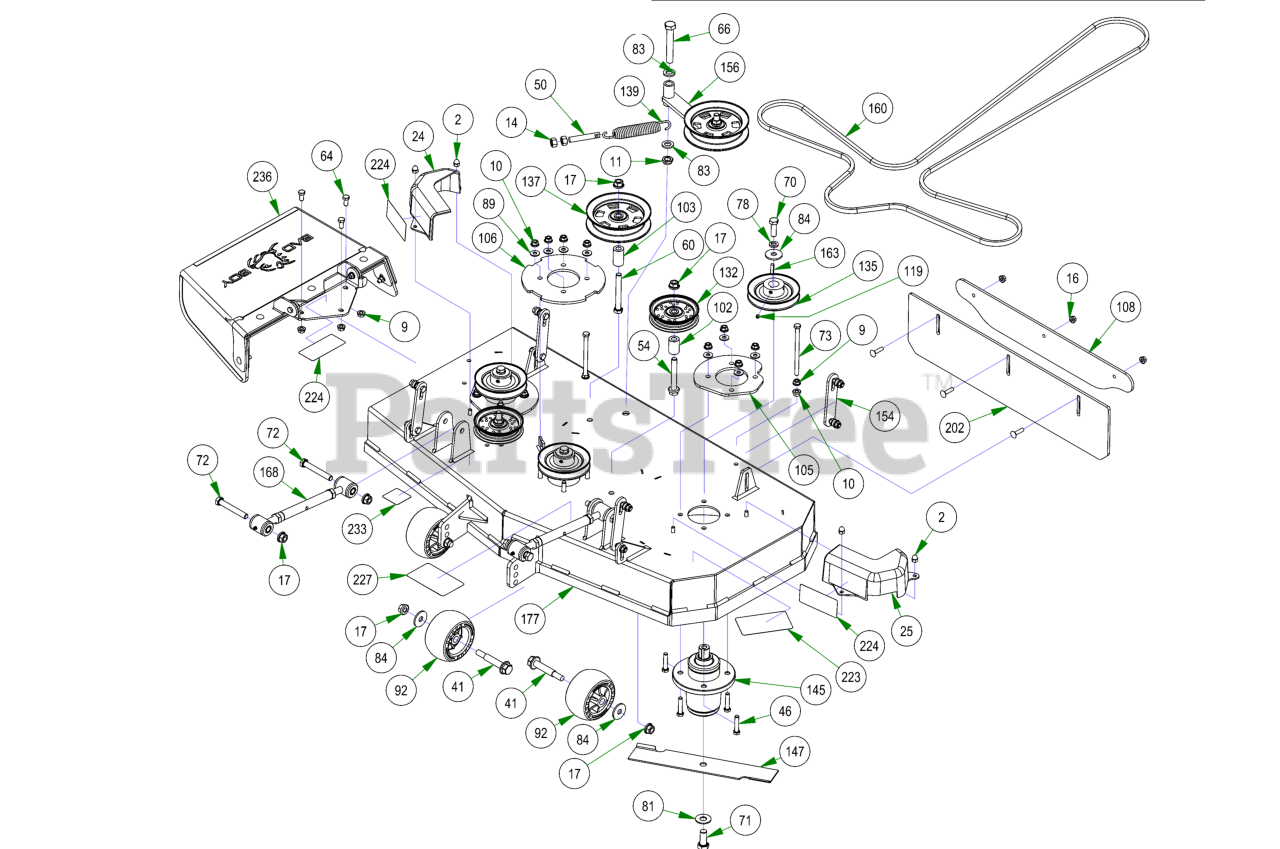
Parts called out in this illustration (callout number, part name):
2	5/16-18 ACORN NUT HIGH-CROWN ZC
9	3/8-16 HEX SERRATED FLANGE NUT HARD/ZINC
10	3/8-16 NYLON INSERT FLANGE LOCKNUT (GR.F) ZINC
11	5/8-11 NYLON INSERT JAM LOCKNUT ZINC
14	1/2-13 HEX NUT ZINC
16	5/16-18 NYLON INSERT FLANGE LOCKNUT ZINC
17	1/2-13 NYLON INSERT FLANGE LOCKNUT ZINC
24	pulley cover chute side
25	pulley cover non-chute side
41	Deck Wheel Bolt
46	3/8-16 X 1-3/4 HEX C/S (GR.5) ZC
50	All Thread
54	1/2-13 X 3-1/2 HEX FLANGE BOLT (GR.8) ZINC
59	5/16-18 X 1-1/4 CARRIAGE BOLT ZINC
60	1/2-13 X 4 HEX CAP SCREW (GR.8) ZINC YELLOW
64	3/8-16 X 3/4 HEX CAP SCREW (GR.5) ZINC
66	5/8-11 X 4 HEX CAP SCREW (GR.8) ZINC YELLOW
70	1/2-20 X 1-1/2 HEX CAP SCREW (GR.5) ZINC
71	5/8-18 X 1-1/2 HEX CAP SCREW (GR.8) ZINC YELLOW
72	1/2-13 X 3-1/2 HEX CAP SCREW (GR.5) ZINC
73	3/8-16 X 5-1/2 HEX CAP SCREW (GR.5) ZINC
78	1/2 SPLIT LOCKWASHER (GR.8) ZINC/YELLOW
81	5/8 USS FLAT WASHER (1-3/4" OD) GR.8 ZINC YELLOW
83	.635 ID X 1.120 OD X .140 THICK FLAT WASHER NYLON
84	1/2 BELLEVILLE WASHER (1-5/8 OD X .140 THK) ZINC
89	5/16 USS FLAT WASHER (7/8 OD) ZINC
92	Deck Wheel
102	.502 ID X .750 OD X 1.500 Long Spacer
103	1 3/4" Pulley Spacer
105	42&48 Deck Spindle Support Plate
106	Deck Spindle Support Plate
108	2023 4" & 5" Stripping Kit Plate
119	5/16-24 X 1/4 SOCKET SET SCREW (CUP PT) PLAIN
132	4 3/4 Idler Pulley - ABFI-76
135	42 Maverick HD Spindle Pulley
137	5-3/4 Idler Pulley
139	Deck Idler Spring
145	OUTLAW SPINDLE ASSEMBLY
147	42'' High lift Blade
154	Deck Hanger Assembly
156	2017 MZ/ZT Deck Idler Assembly
160	2023 42" Deck Belt
163	1/4 X 1 SQ MACHINERY KEY 1018 STL PLN
168	2018 Maverick Turnbuckle (Top Link)
177	2023 42" x 5" Deck
202	2023 ZT Stripping Kit Rubber
223	2018 42" MZ/Comp Out Deck Decal
224	Danger Decal-Spindle/Discharge
227	Deck Belt Route Decal
233	Deck Impact Patent Decal 9591803
236	ZT Chute Assembly
